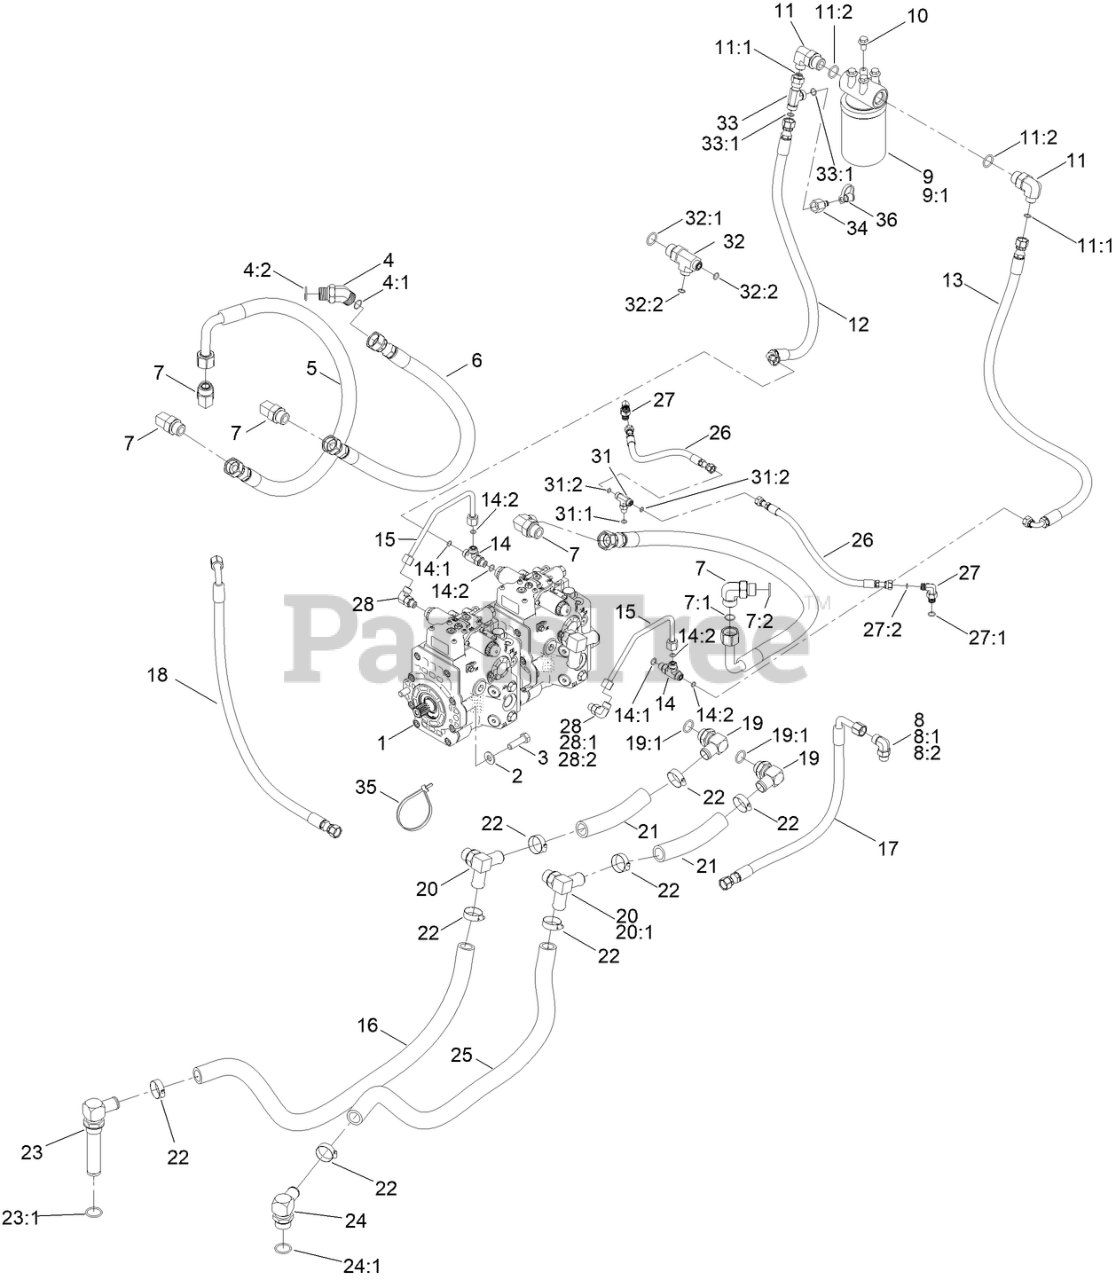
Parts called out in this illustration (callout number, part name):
1	HYD PUMP ASM
2	WASHER-THRUST
3	SCREW-HH
4	FITTING-45 DEG
4:1	O-RING
4:2	O-RING
5	HYD HOSE ASM
6	HYD HOSE ASM
7	FITTING-ELBOW-90
7:1	O-RING
7:2	O-RING
8	FITTING-ELBOW, 90 DEG
8:1	O-RING
8:2	O-RING
9	FILTER-OIL
9:1	FILTER-HYD
10	SCREW-HHF
11	FITTING-HYD, 90 DEG
11:1	O-RING
11:2	O-RING
12	HYD HOSE ASM
13	HYD HOSE ASM
14	FITTING-TEE
14:1	O-RING
14:2	O-RING
15	HYD TUBE ASM
17	HYD HOSE ASM
18	HYD HOSE ASM
19	FITTING-90
19:1	O-RING
20	CONNECTOR
20:1	O-RING
22	CLAMP-HOSE
23	STRAINER FITTING ASM
23:1	O-RING
24	STEM-BARB-90
24:1	O-RING
26	HYD HOSE ASM
27	FITTING-ELBOW, 90 DEG
27:1	O-RING
27:2	O-RING
28	FITTING-ELBOW, 90 DEG
28:1	O-RING
28:2	O-RING
31	FITTING-TEE
31:1	O-RING
31:2	O-RING
32	FITTING-TEE
32:1	O-RING
32:2	O-RING
33	FITTING-HYD, TEE
33:1	O-RING
34	FITTING
35	TIE-CABLE
